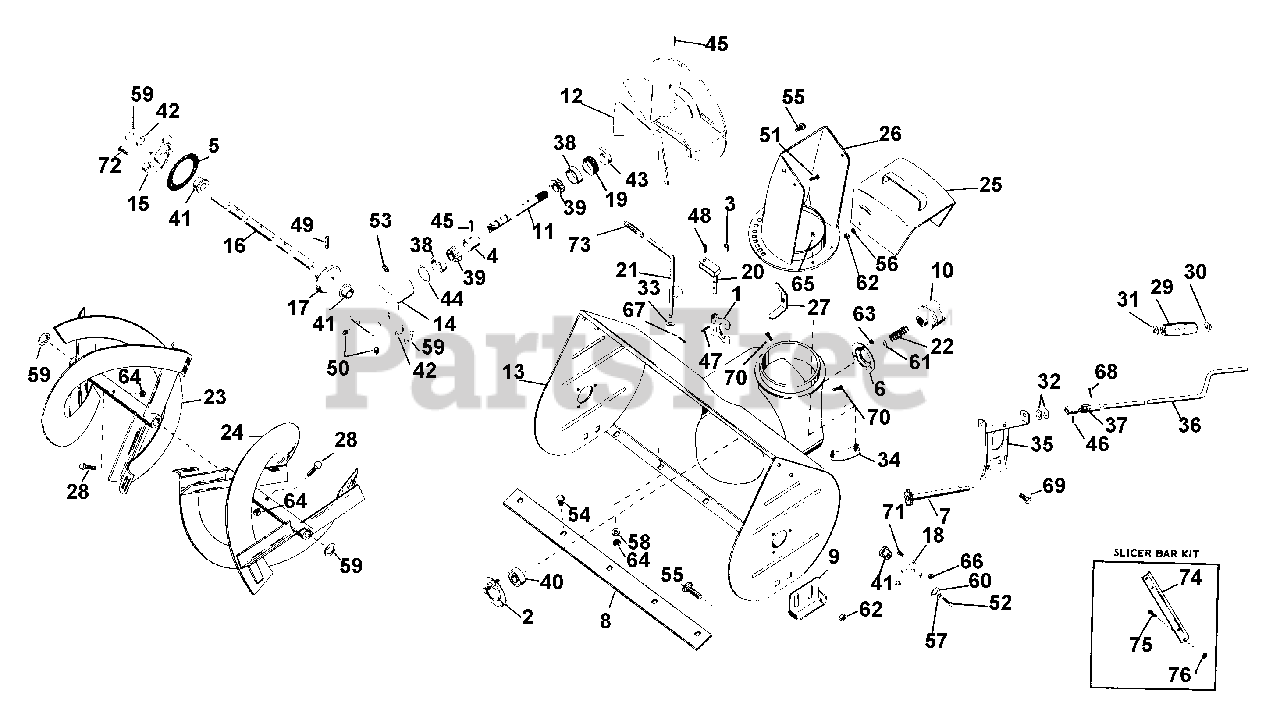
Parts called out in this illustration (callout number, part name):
1	CLUTCH FORK
2	BEARING FLANGE
4	BEARING SPACER
6	BEARING FLANGE
7	CONTROL SPROCKET
8	SCRAPER BLADE 24"
9	RUNNER
10	JAW CLUTCH
11	HELICON PINION SHAFT
13	BLOWER HOUSING
14	CASE, GEAR - C.I.
15	GEAR CASE FLANGE
16	FRONT GEAR SHAFT
17	HELICON GEAR - 41 TOOTH
18	BEARING SUPPORT
19	ADJUSTMENT PLUG
20	FORK SHAFT
21	FORK CAM
22	SPRING
23	R H RAKE
24	L H RAKE
25	DEFLECTOR CHUTE
26	DISCHARGE CHUTE
27	WING NUT
28	SHEAR BOLT YWZC
30	CAP, 3/8 ROD YWZC
31	FASTENER
32	WAVE WASHER .515 X 1.00 X .125
33	WAVE WASHER .406X.750X.063FH
34	CHUTE CLAMP
35	CHUTE CNTL BRACKET
36	CHUTE CNTL CRANK
37	UNIVERSAL JOINT
38	BRG-CUP 1.781X.475
39	BRG-CONE .750X.61
40	BRG-BALL .750X1.750X.50
41	BSHG-FLG 1.000X1.12X.62X1.50BR
42	SEAL 1.000X1.312X.150
43	SEAL .750X1.499X.225
44	RG-RTNG INT 1.781 HSG X.062
45	PIN-ROLL .250X1.25
46	PIN-ROLL .125X1.00
47	PIN-ROLL .250X1.25
48	PIN-ROLL .250X1.25
49	PIN-ROLL .313X1.38
50	PIPE PLUG
51	BLT-HEX .31-18X.63 PL GR 2
52	BLT-HEX .31-18X.63 PL GR 2
53	SCR-SET .38-16X.50 SKHCUP OH
54	BLT-RDHDSQSHNK .31-18X.50 YZ
55	BLT-RDHDSQNK .38-16X.75 SHT PL
56	WSHR-LK .375X.115 HVY PL
57	WSHR-LK .500X.151 HVY PL
58	WSHR-FL-STL .38X.875X.083 PL
59	BRG-CUP 2.328X.465
60	BRG-CONE 1.25X.66
61	BRG-CUP 3.346X.532
62	NUT-LK-CTR .375-16 GR A PL
63	NUT-LK-CTR .250-20 PL
64	NUT-LK .312-18 GR A PL
65	NUT-KEPS 10-24 PL
66	NUT-LK-FLG .250-20 PL
67	PIN-COTR .12X1.0 PL
68	PIN-COTR .09X.75 PL
69	BLT-SERHFWH .31-18X.50 PL
70	BLT-SCRHFWH .38-16X.50 PL
71	SCR-SLTR-SERNK .25-20X.62 PL
72	BLT-SERHFWH .25-20X.75 PL
74	CUTTER BAR
75	BLT-RDHDSQSHNK .31-18X.50 YZ
76	NUT-LK .312-18 GR A PL
